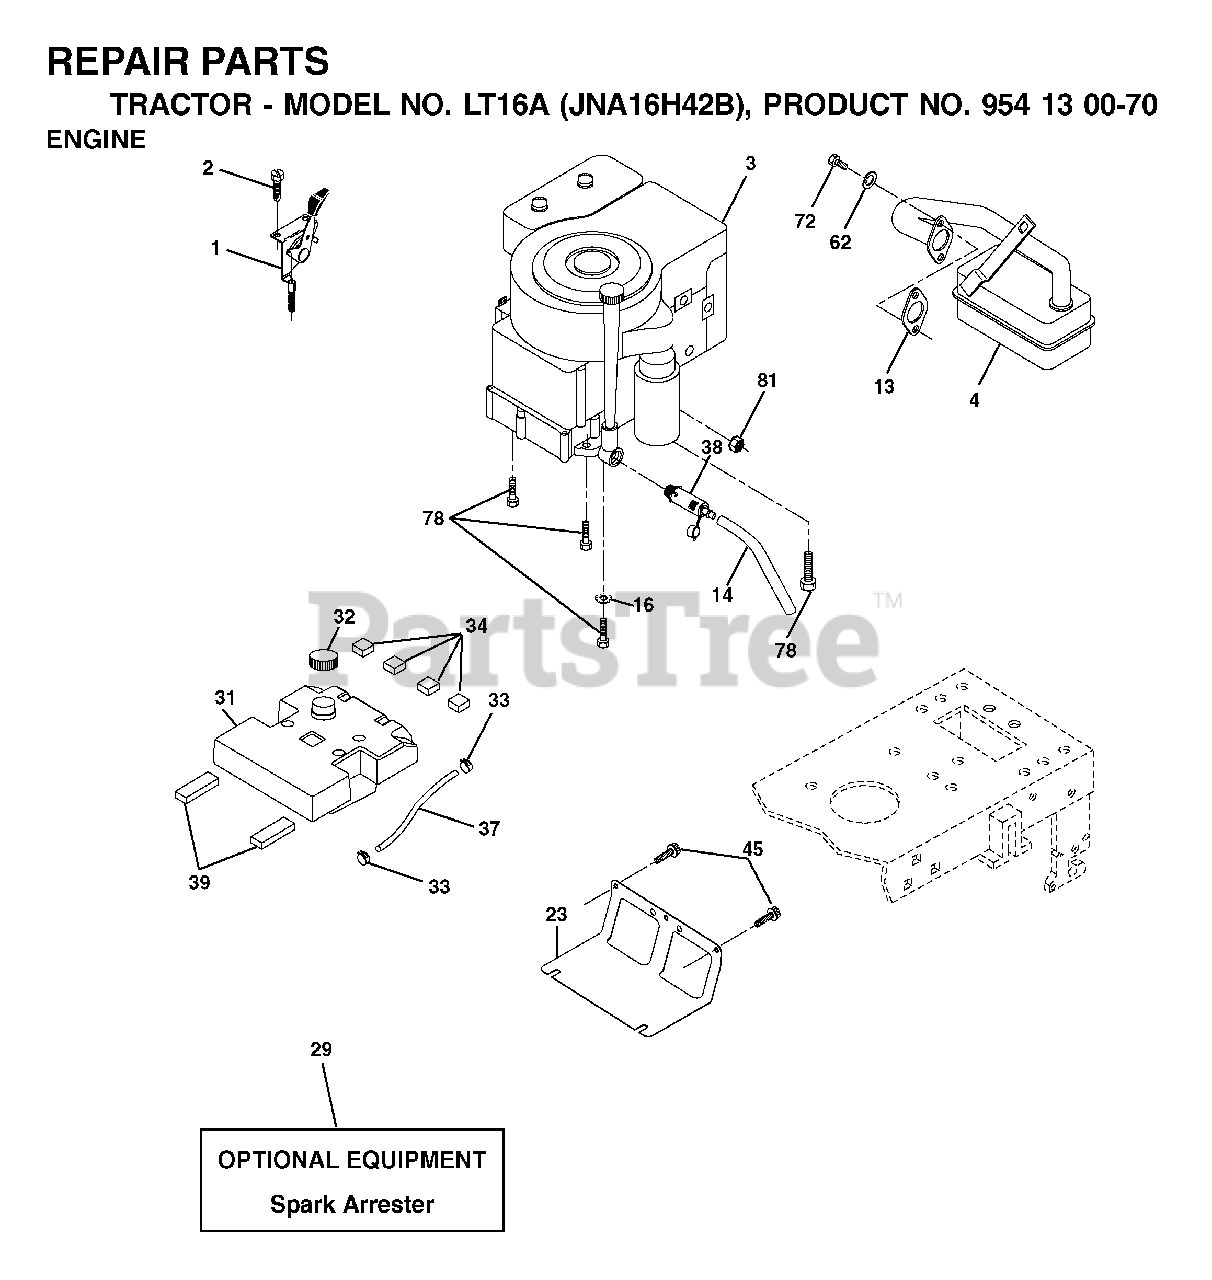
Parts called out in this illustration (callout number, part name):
1	CONTROL TH/CH FLAG
2	SCREW
13	REPL BY 532 27 22-93
14	TUBE, DRAIN OIL ASM.
16	LOCKWASHER
23	SHEILD.BROWNING.DBR.GUARD
29	ARRESTER SPARK (OPTIONAL)
31	TANK.FUEL(3.5.GAL)
32	FUEL CAP
33	HOSE CLAMP
34	PAD-SPACER LT
38	PLUG, OIL DRAIN EASY
39	PAD IDLER TI
45	SCREW, 3/8-16X3/4
62	LOCKWASHER
72	SCREW
78	SCREW.3/8-16
81	NUT
